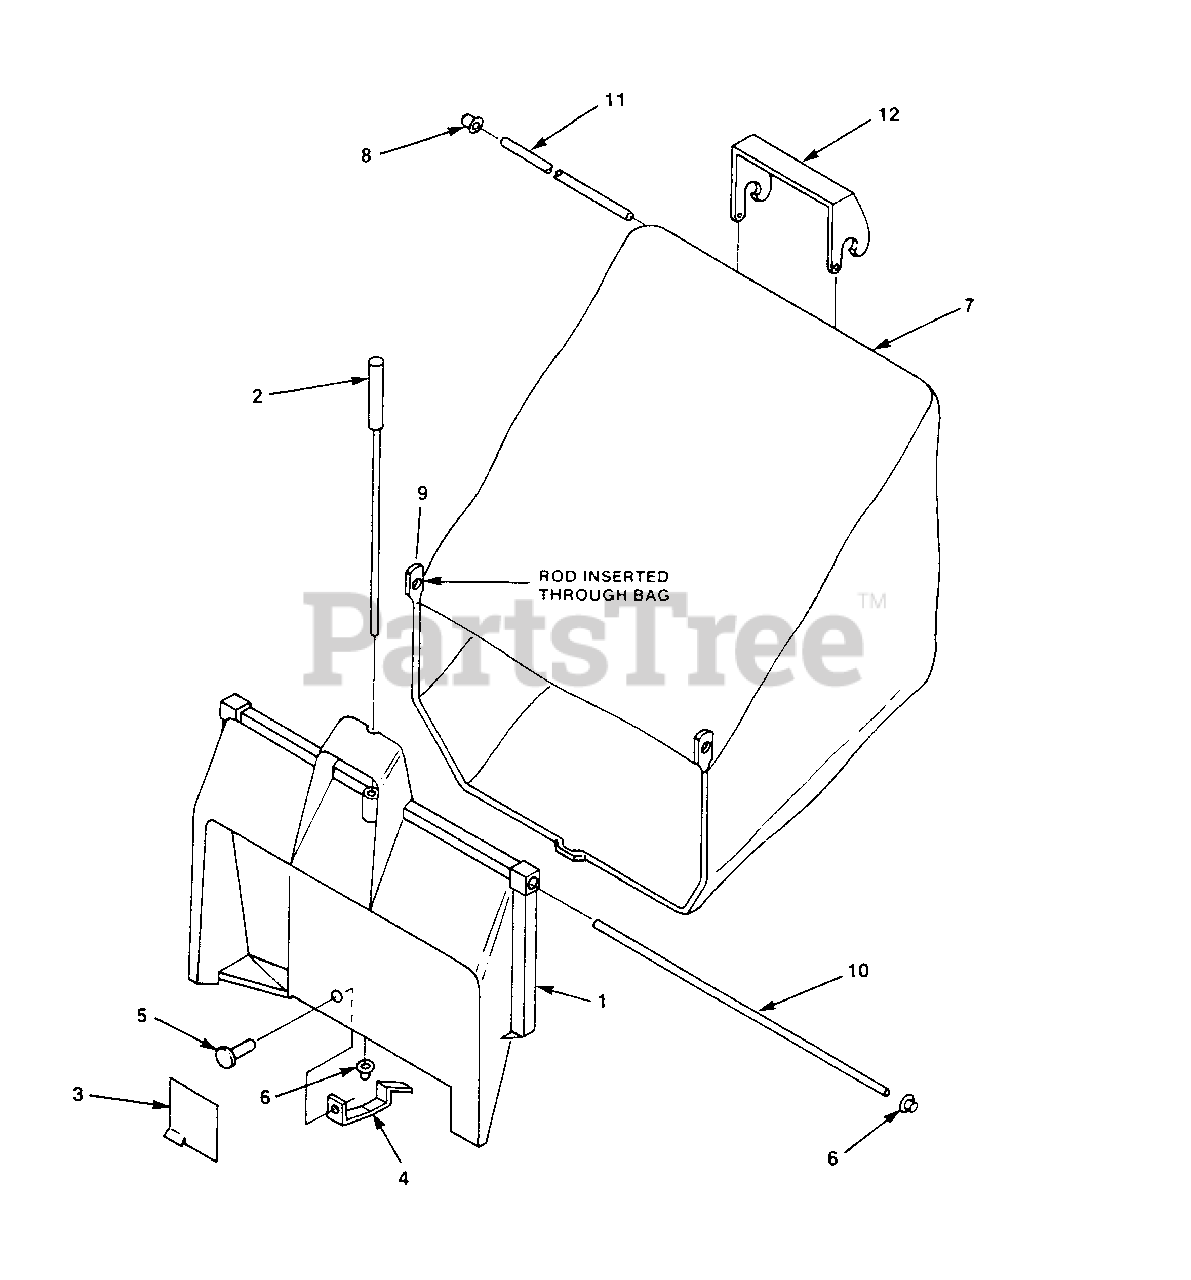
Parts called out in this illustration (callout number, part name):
1	ADAPTOR- Bag
2	ROD- Latch release
3	DEFLECTOR
5	RIVET- Pop 5/32 x 3/8"
7	CATCHER-GRASS
8	END- Rod (Retainer Up-bag)
9	ROD- ZP Bag support
10	ROD- ZP Bag hinge
11	ROD- ZP Upper bag
12	HANDLE- Upper bag
